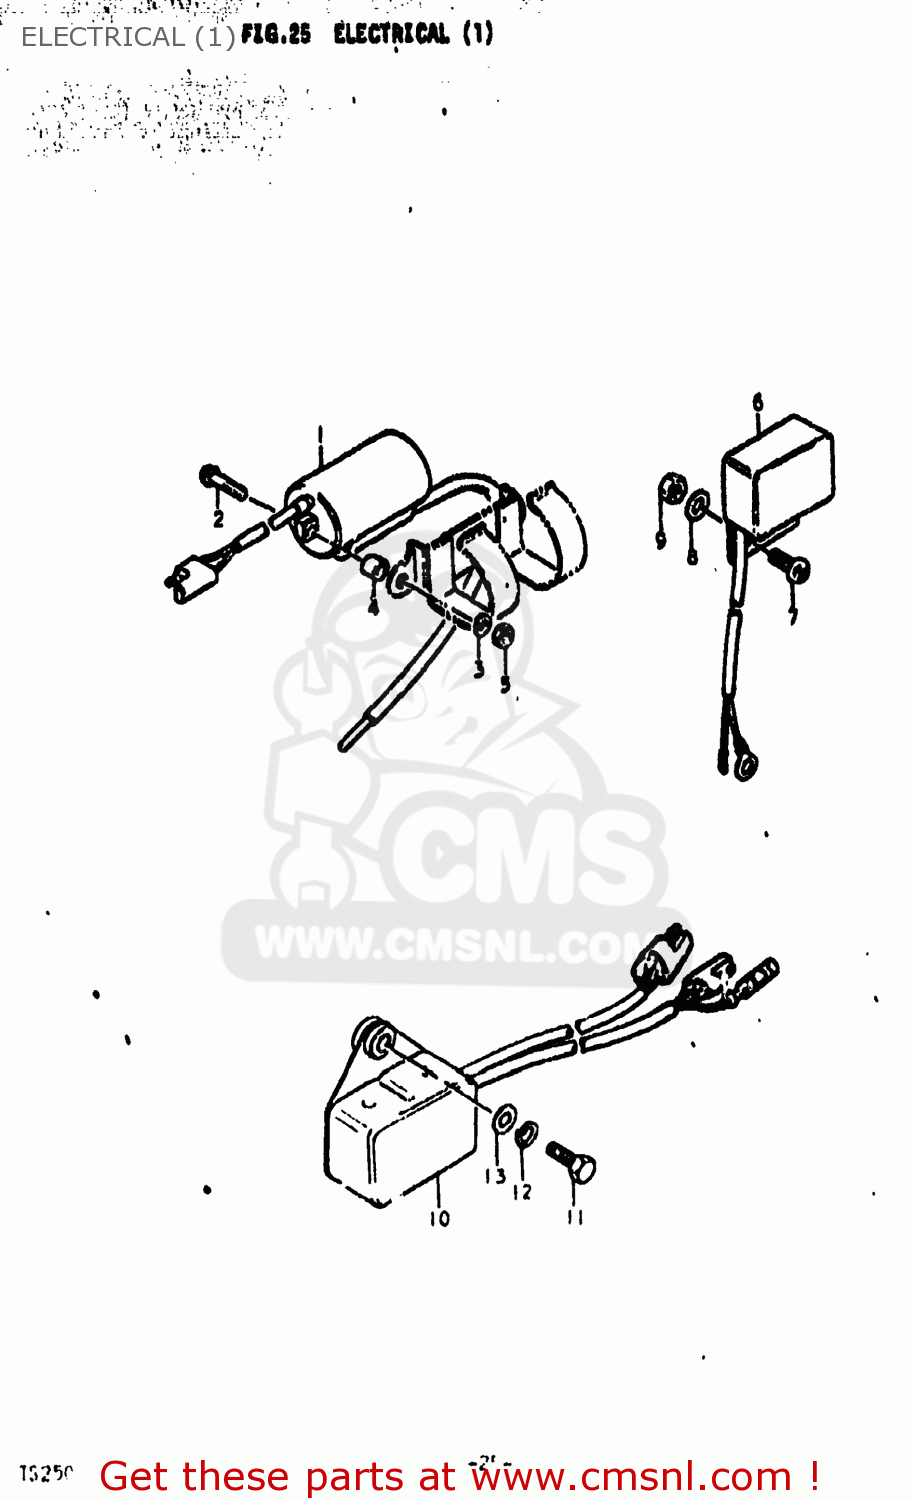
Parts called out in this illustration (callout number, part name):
1	COIL ASSEMBLY,IGNITION
2	SCREW
3	LOCK WASHER
4	SPACER
5	NUT
6	REGULATOR ASSEMBLY
7	SCREW 6X12
8	WASHER
9	NUT
10	CDI UNIT ASSY
11	BOLT(6X20)
12	LOCK WASHER
13	WASHER
